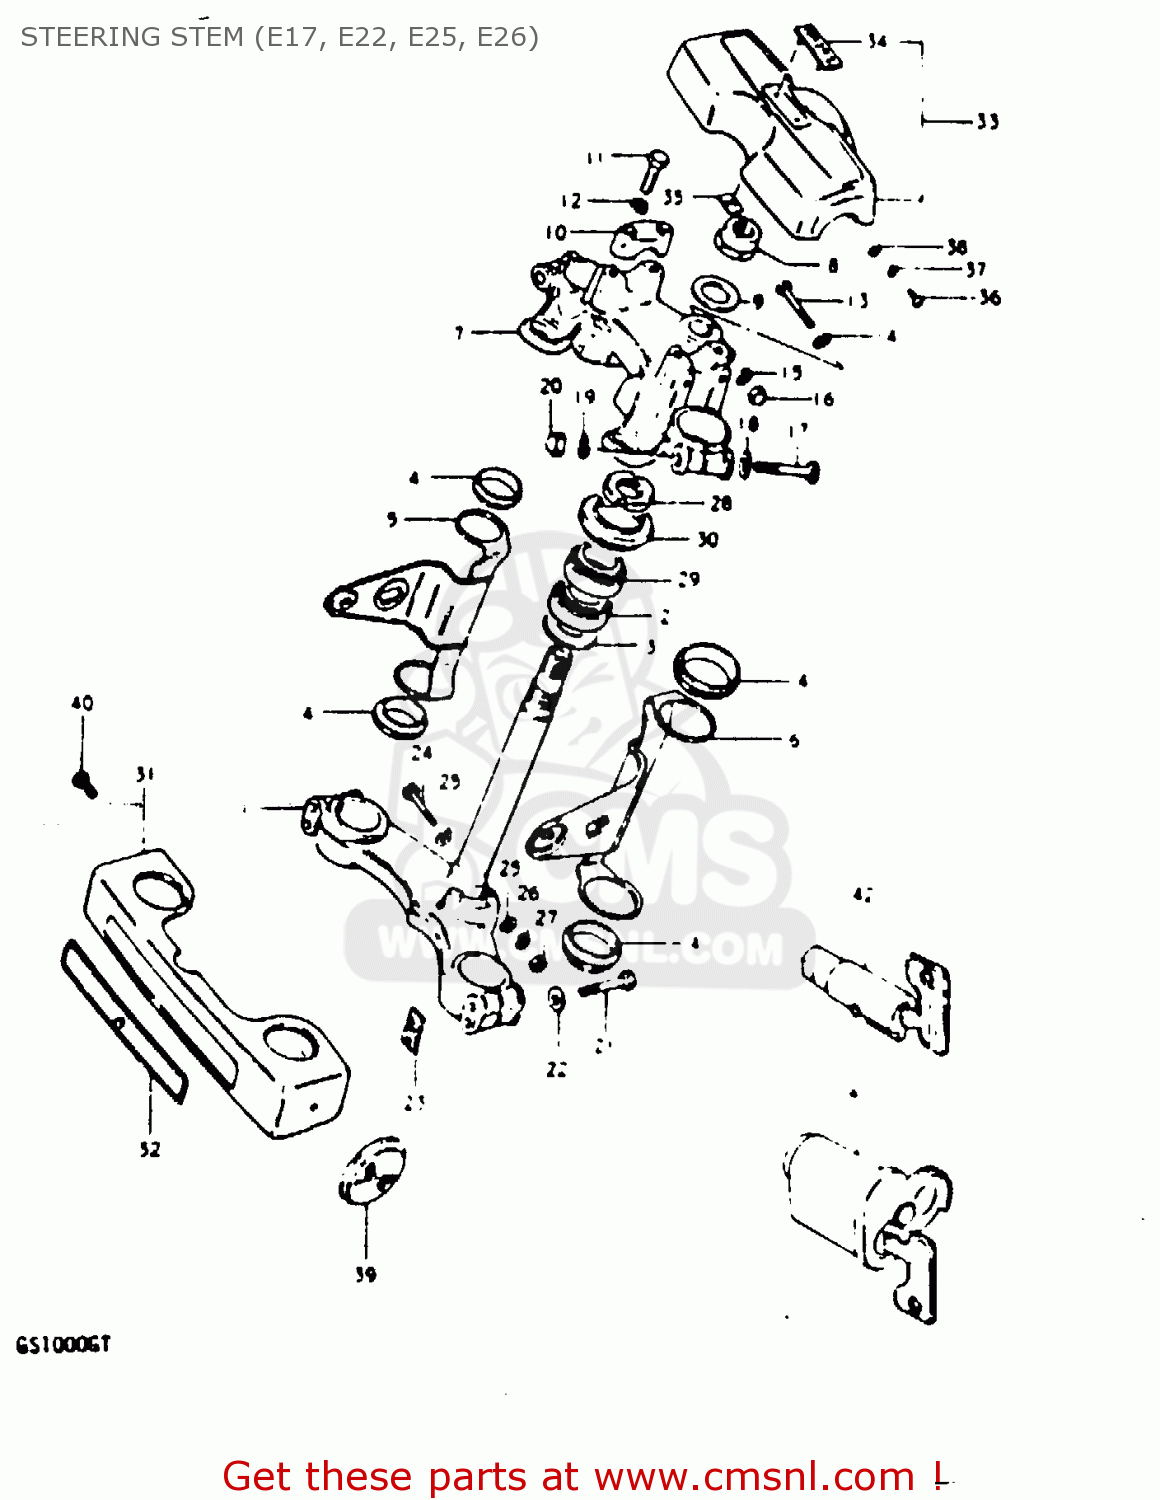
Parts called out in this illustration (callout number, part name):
1	STEM,STEERING
2	BEARING
3	WASHER,THRUST
4	CUSHION,HEADLAMP BRACKET
5	BRACKET,HEADLAMP,RIGHT
6	BRACKET,HEADLAMP,LEFT
7	HEAD,STEERING STEM
8	NUT,FR FORK UPR BRACKET
9	WASHER
10	HOLDER,HANDLE(BLACK)
11	BOLT
12	LOCK WASHER
13	BOLT 8X50
14	WASHER
15	LOCK WASHER
16	NUT
17	BOLT 10X55
18	WASHER
19	LOCK WASHER
20	NUT, LOWER LH
21	BOLT 8X55
22	WASHER
23	NUT,FR FORK INNER TUBE
24	BOLT
25	WASHER
26	LOCK WASHER
27	NUT
28	NUT,STEERING STEM(25X44X10)
29	TAPER,ROLLER BEARING
30	DUST SEAL,STEERING,UPPER
31	COVER,FRONT FORK
32	EMBLEM
33	PAD,HANDLEBAR
34	EMBLEM,HANDLE COVER PAD
35	NUT
36	SCREW
37	LOCK WASHER
38	WASHER
39	REFLEX REFLECTOR,RR
40	SCREW 5X6
41	LOCK ASSY, STEERING (NEIMAN TYPE EXECUTE
42	LOCK ASSEMBLY,STEERING (NEI
